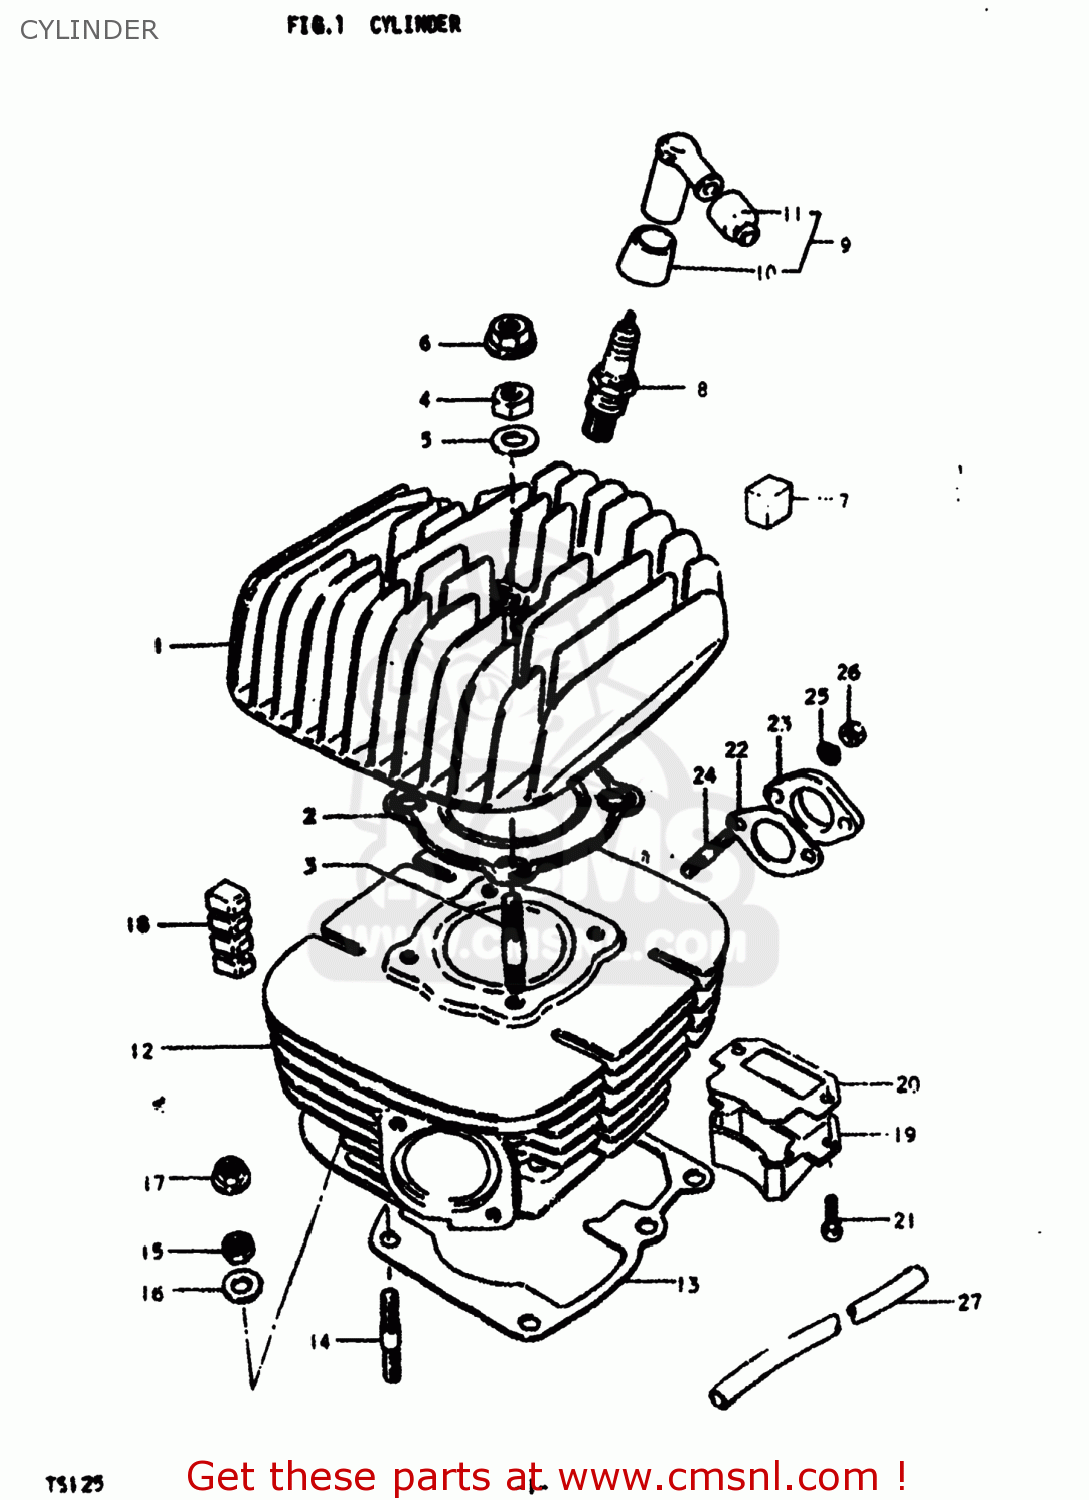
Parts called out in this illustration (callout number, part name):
1	HEAD,CYLINDER
2	GASKET,CYLINDER HEAD (MCA)
3	STUD BOLT
4	NUT (8MM)
5	WASHER
6	NUT
7	PAD,CYLINDER
8	PLUG,SPARK
9	CAP,SPARK PLUG
10	SEAL,SPARK PLUG
11	SEAL,SPARK PLU
12	CYLINDER
13	GASKET,CYLINDER (MCA)
14	STUD 8X25
15	NUT
16	WASHER
17	NUT
18	PAD,CYLINDER
19	VALVE ASSEMBLY,REED
20	GASKET,REED VALVE (MCA)
21	SCREW
22	GASKET,CARBURETOR (MCA)
23	INSULATOR,CARBURETOR
24	STUD BOLT
25	WASHER,LOCK,8.
26	NUT
27	HOSE
